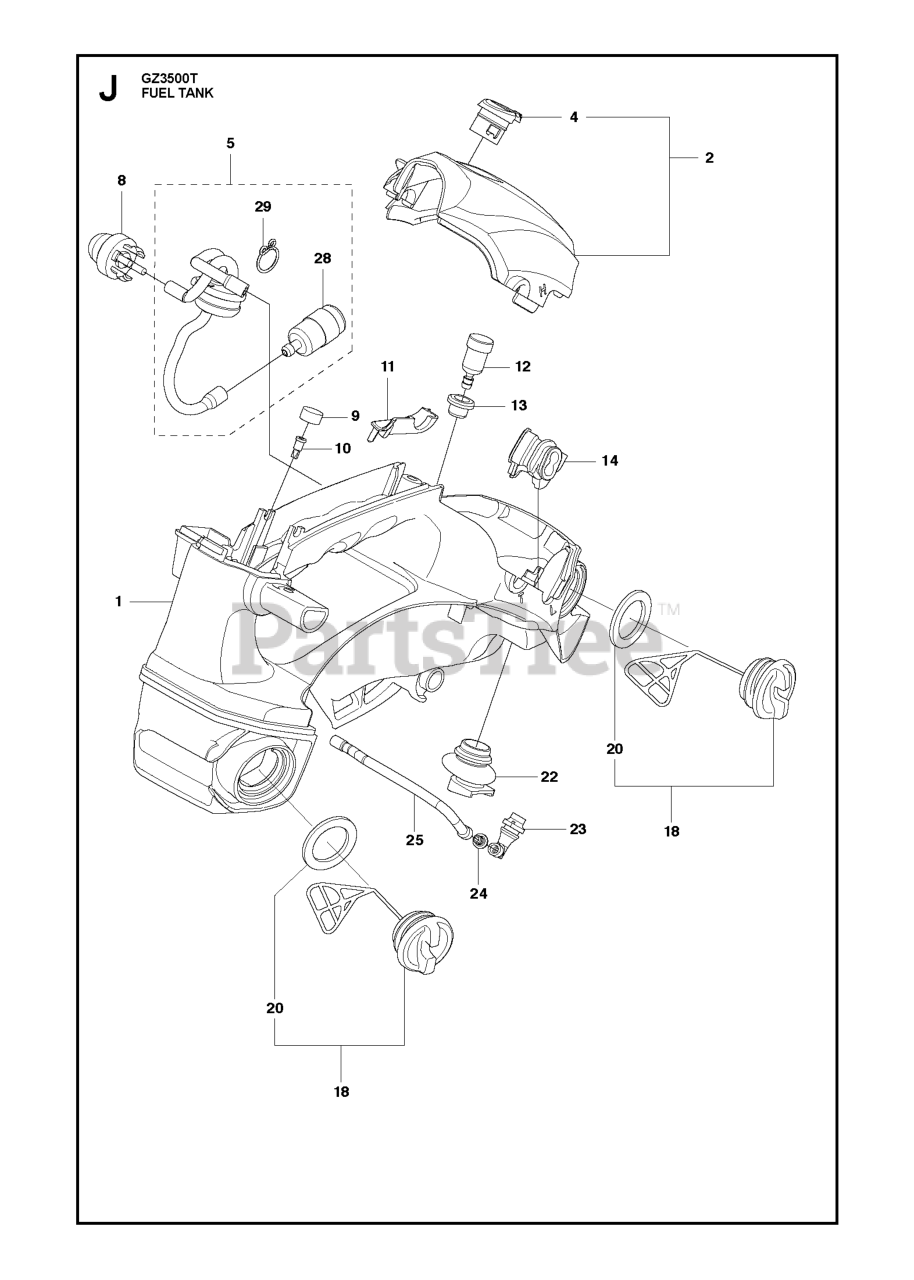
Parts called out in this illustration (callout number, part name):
1	HANDLE
2	COVER COMP
5	PIPE COMP
8	PRIMARY BTN
9	BREATHER SEAL
10	AIR CONTROL BREATHER
12	BREATHER
13	GROMMET
14	GUIDE CARB
18	CAP ASSY
22	PIPE, AIR
23	PIPE
25	PIPE
28	FUEL FILTER
29	CLIP
